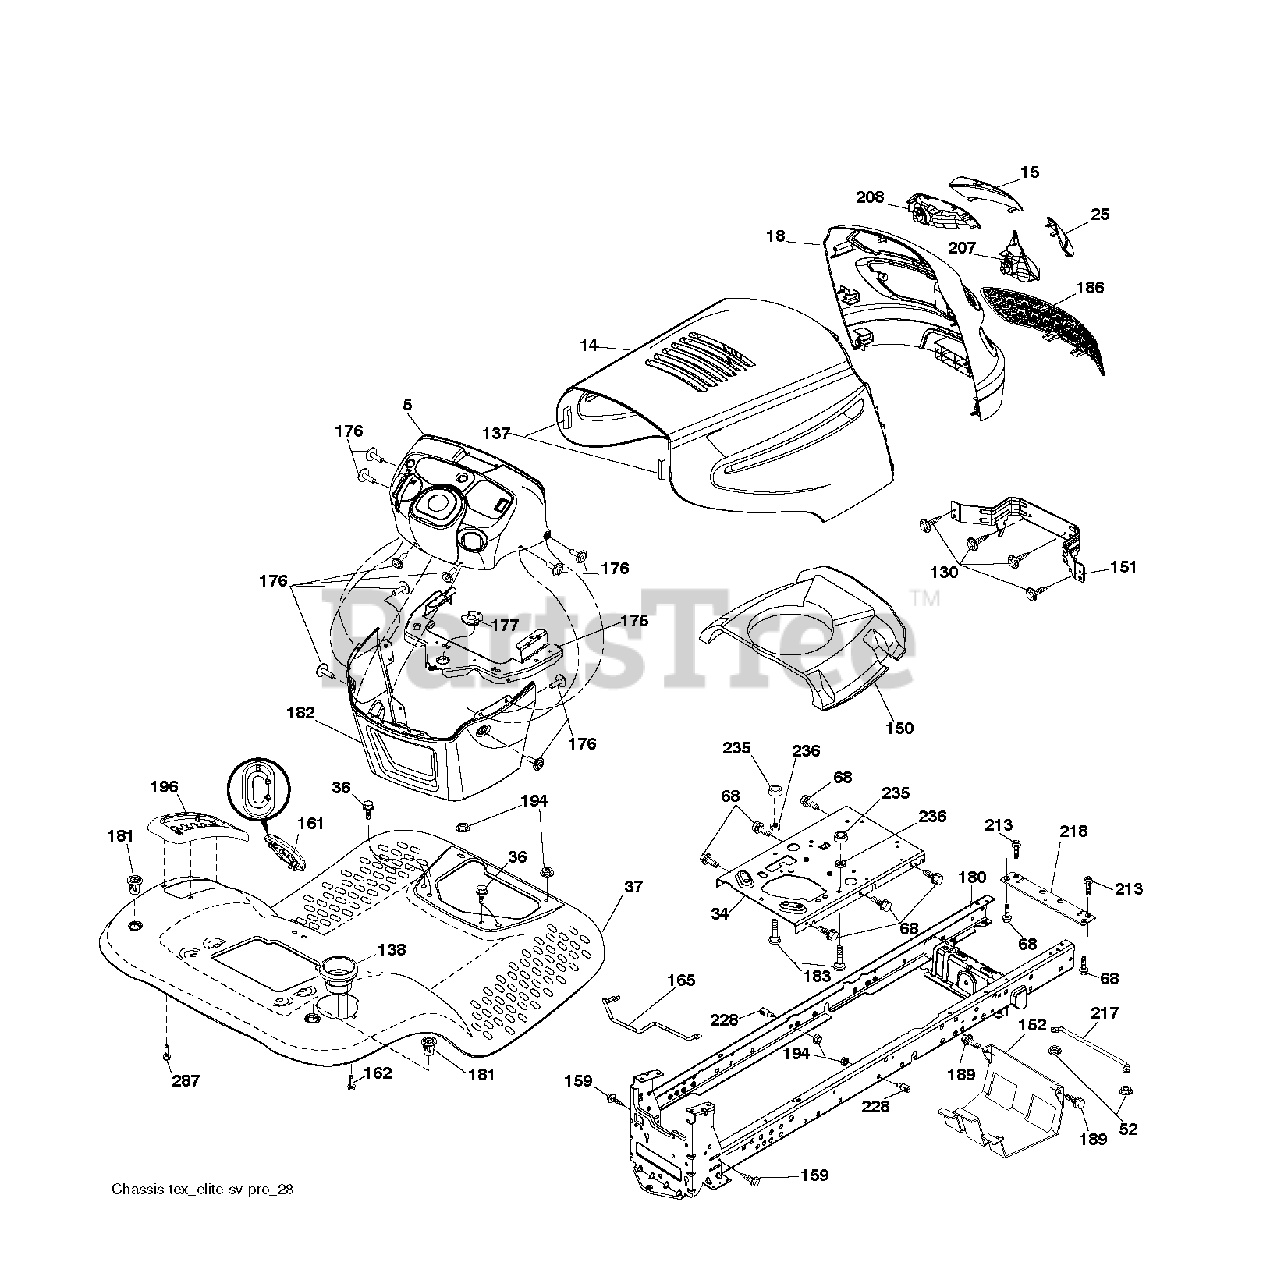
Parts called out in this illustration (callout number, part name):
34	PLATE.ENGINE.WELDED.CHASSIS
36	SCREW 5/16"
52	LOCKNUT
130	SCREW.#10 X 0.750.BOS THREAD
137	BUMPER.HOOD.LARGE.1.75"
138	CUPHOLDER.TL.TEX.BLACK
151	BRACKET PIVOT
152	SHIELD BROWNING
159	SCREW, 3/8-16X3/4
161	WINDOW.FUEL.LT.TEX.BLACK
162	SCREW.HI-LO.CONSOLE
165	SUPPORT.TANK.REAR.W/TE
175	CROSSMEMBER.LT
176	SCREW.#10-24X5/8.RN.QU
177	BUSHING STEERING
180	CHASSIS
181	FEND/FTRST.PCH.CPH.NFW
182	DASH.LOWER.LT.CCS
183	BOLT.5/16-18X1-1/4 FULL THD
189	SCREW
194	NUT LOCK HEX FLANGE 5/16-18
207	BEZEL GRILL RH
208	BEZEL GRILL LH
213	BOLT
217	ROD.PIVOT.HOOD
218	X-PIECE.HOOD.STOP.NON/
228	STUD.FASTNER.W/ANTI-ROTATE
235	SPACER FENDER
236	NUT.CENTERLOCK.5/16-
